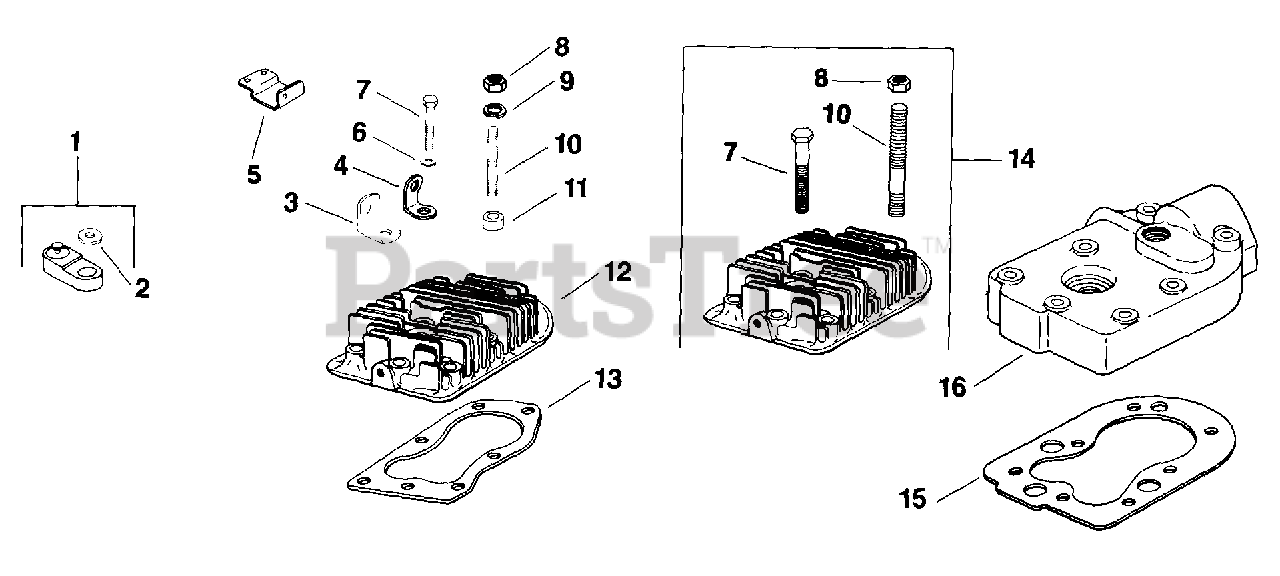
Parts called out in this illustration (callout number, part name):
4	STRAP - USE 28 445 01
6	WASHER, FLAT 5/16"
7	SCREW, SEMS 1/4-20X5/8" USE 25 086 539-S
14	KIT, CYLINDER HEAD
